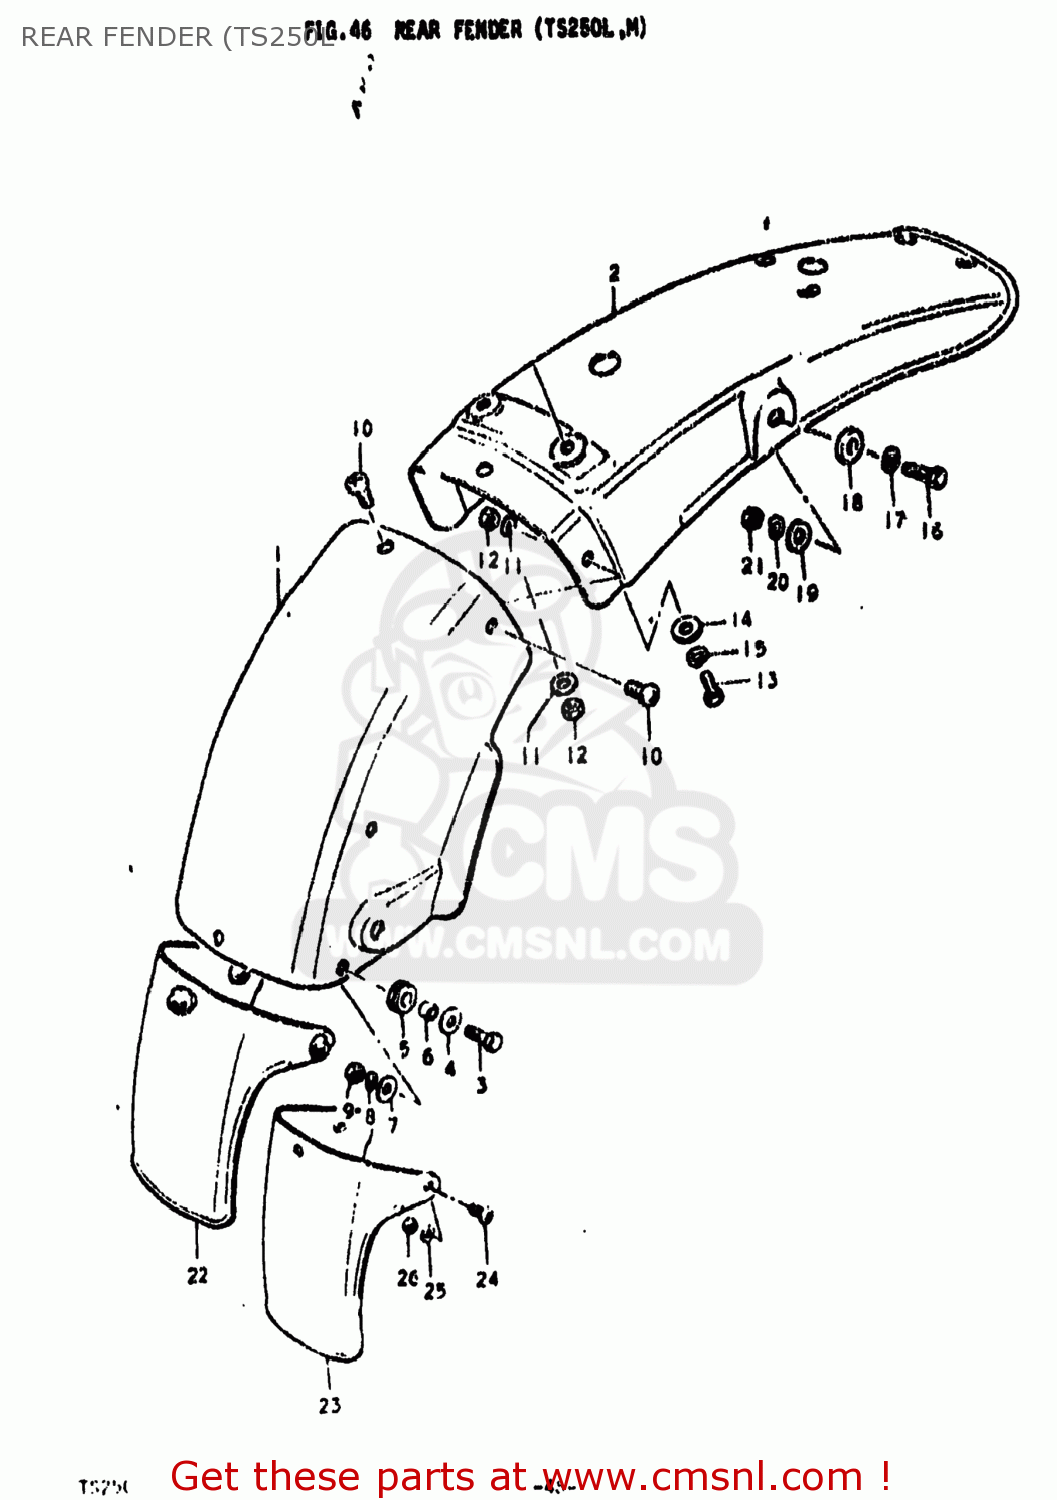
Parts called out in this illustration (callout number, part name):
1	FENDER,REAR
2	FENDER,REAR
3	BOLT
4	WASHER (6.5X20X1.2)
5	CUSHION
6	SPACER(6.1X9X7.5)
7	WASHER
8	LOCK WASHER
9	NUT
10	SCREW
11	WASHER
12	NUT
13	BOLT
14	WASHER
15	LOCK WASHER
16	BOLT
17	SPACER
18	WASHER
19	WASHER
20	LOCK WASHER
21	NUT
22	STAY SET,MUD FLAP,REAR
23	MUD GUARD,REAR FENDER
24	SCREW
25	WASHER
26	NUT
